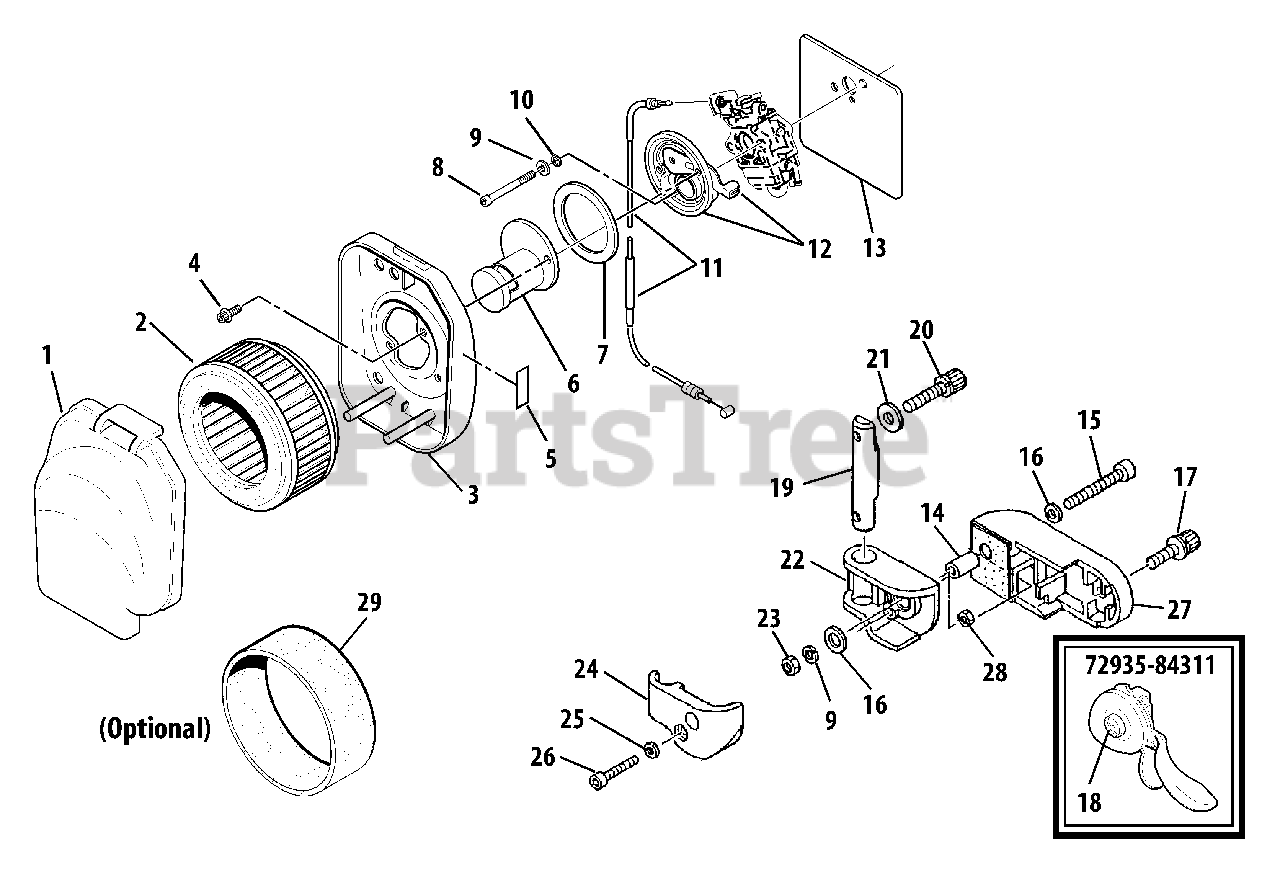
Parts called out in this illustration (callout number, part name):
1	COVER, AIR FILTER
2	FILTER, AIR
3	CASE, AIR FILTER
4	SCREW - 4X14
5	LABEL - CHOKE
6	ADAPTOR, INTAKE
7	GASKET
8	SCREW - 5X60
9	LOCKWASHER - 5
10	WASHER - 5
11	CABLE, THROTTLE
12	CHOKE ASSY
13	GASKET, INTAKE
14	COLLAR
15	SCREW - 5X25
16	WASHER
17	SCREW - 6X16
18	SCREW
20	SCREW - 6X16
24	COVER
25	WASHER - 4
26	SCREW - 4X20
27	BRACKET
28	NUT - 4
29	PRE-FILTER
72935-84311	THROTTLE LEVER ASSY
